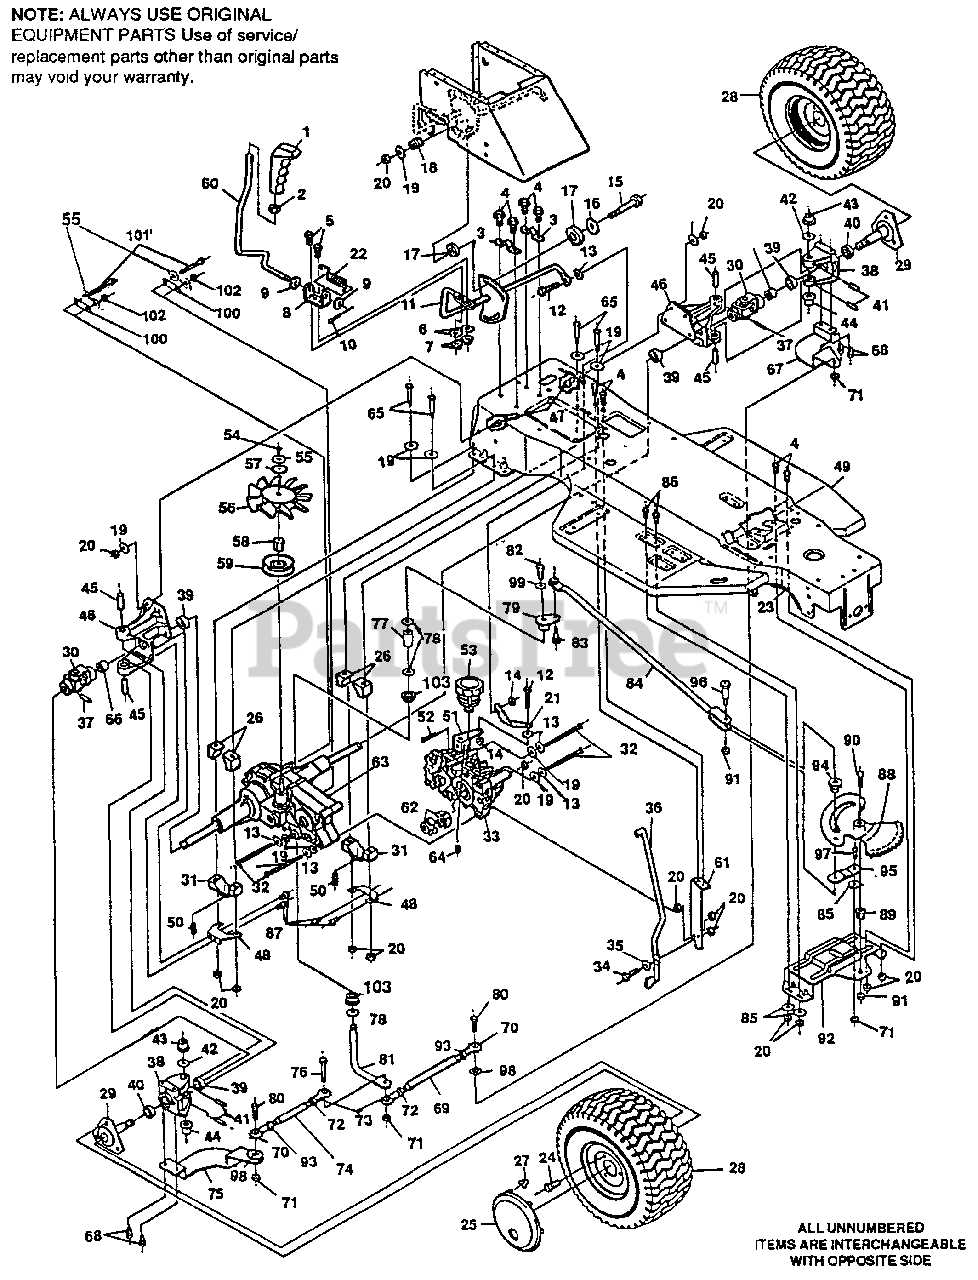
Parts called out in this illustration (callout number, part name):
1	Handle, Deck Engage Lever
2	Nut, 1/4-13
3	Bracket, Clutch/Brake Arm
4	Screw, 5/16-18 x 1/2 In.
5	Screw, 1/4-20 x .62 In.
6	Flatwasher
7	Nut, 1/4-20
8	Bracket, Shift
9	Washer, Flat
10	Pin, Cotter
11	Shift Rod Assembly
12	Screw, 3/8-16 x 1-1/4 In.
14	Nut, 3/8-16 Thd.
15	Screw, 5/16-18 x 2 In.
16	Washer, Flat
17	Washer, Friction
19	Washer, Flat
20	Nut, 5/16-18 Thd.
21	Shift Link
22	Spring, Torsion
24	Screw, Hx Hd, 1/2-20 x 1/2 In.
25	Hubcap, 8 In.
26	Mounting Block
27	Clip, Hubcap
28	Tire and Wheel Assembly
28	Valve System
29	Hub Assembly
30	U-Joint Assembly
31	Mounting Block
32	Screw, 5/16-18 x 4-1/2 In.
33	Hydrostatic Pump
34	Shoulder Bolt
36	Rod- Relief Valve
37	Pin, Grooved, 1/4 x 1 1/2 In.
38	Bracket, Steering Pivot, Outer
39	Bearing
41	Pin, Spring 1/4 x 1 1/2 In.
42	Washer, Flat
43	Bushing, Shouldered
44	Bushing, Shouldered
45	Pin, Steering Hinge
46	Bracket, Steering Pivot, Inner
47	Screw, Hx Hd , 5/16-18 x 1 In.
48	Bracket, Transaxle Mounting
49	Main Frame
50	Screw, #10-32 x 1/4 In.
51	Armspeed Control
52	Pin, Spring
53	Reservoir, Hydro
54	Screw, 1/4-20 x 1/2 In.
55	Washer, Split Lock
57	Washer, Flat
58	Nut, Pulley 1/2-20 and 1/4-20
59	Pulley, Assy. Hydro
60	Shift Rod
61	Stabilizer Bracket
62	Coupling
63	Transaxle
64	Set Screw
65	Screw, 5/16-18 x 2.75 In.
67	Arm, Rear Wheel Steer, L.H.
68	Screw, Self-Tap 3/8-16 x 3/4 In.
69	Tie Rod, L.H.
70	Tie Rod End, L.H.
71	Nut, Hex, Ctrlk, 3/8-24
72	Nut, Hex Jam, 3/8-24
74	Tie Rod End, R.H.
75	Arm, Rear Wheel Steer, R.H.
76	Screw, 3/8-24 x 1 3/4 In.
78	Washer, Lat 49/64 In.
79	Steering Pivot
80	Screw, 3/8-24 x 1 1/4 In.
81	Shaft, Steering Pivot
82	Screw 5/16-24 x 1 In.
83	Bolt, Shoulder 3/8-24
84	Rod Assembly, Rear Wheel Steer
85	Washer, Flat 3/8 In.
86	Screw, Self-Tap 5/16-18 x 3/8 In.
87	Screw, Self-Tap 5/16-18 x 5/8 In.
88	Assembly Sector Gear
89	Bushing, Sector Gear
90	Screw, 1/2-20 x 2 3/8 In.
91	Nut, Hx, Ctrlk 1/2-20
92	Plate, 4-Wheel Steer Pivot
93	Nut, Jam 3/8-24
94	Cam Yoke Roller
95	Arm, Roller Swing
96	Shoulder Bolt, Cam Roller
97	Shoulder Bolt, Cam Follower Arm Pivot
98	Washer, Split Lock
99	Washer Flat
100	Bracket, Rear Pivot
101	Screw 1/4-20 x .75 In
102	Nut 1/4-20
103	Bearing Spindle
